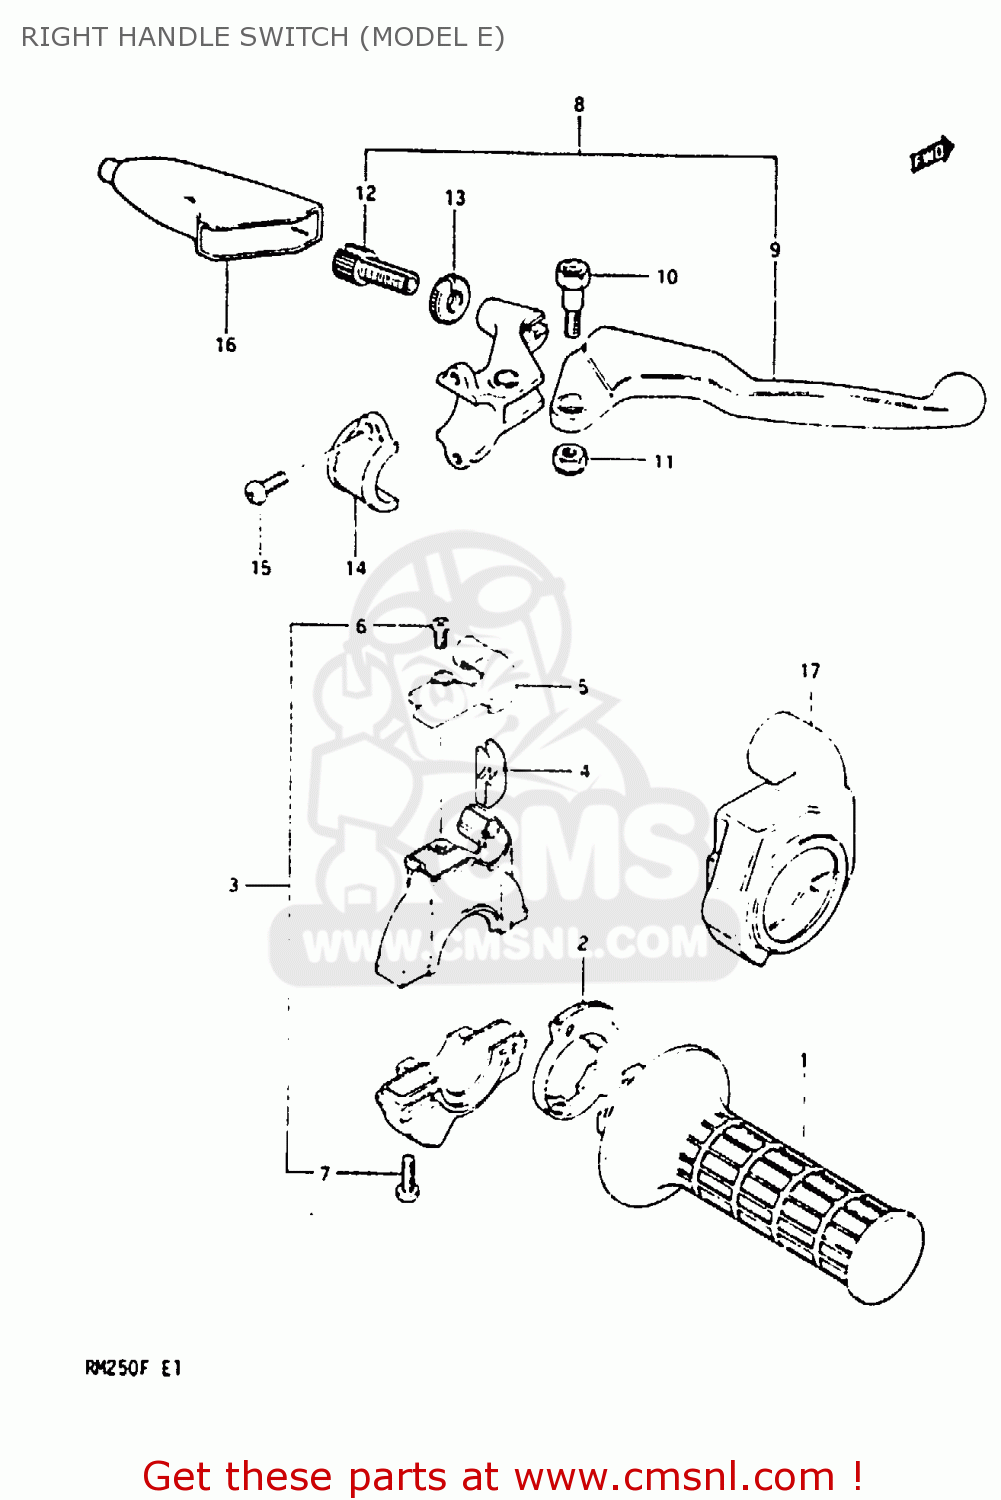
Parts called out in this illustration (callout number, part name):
1	GRIP,THROTTLE
2	ROTOR,THROTTLE GRIP
3	CASE ASSY,THROTTLE
4	GUIDE PIECE,THROTTLE
5	COVER,THROTTLE CASE
6	SCREW
7	SCREW
8	LEVER ASSEMBLY,BRAKE
9	LEVER,BRAKE
10	BOLT,LEVER
11	NUT 6MM
12	ADJUSTER,CABLE
13	NUT,CABLE ADJUSTER
14	BRACKET,CLUTCH LEVER HOLDER
15	SCREW
16	COVER,CLUTCH LEVER
17	COVER,THROTTLE CASE
